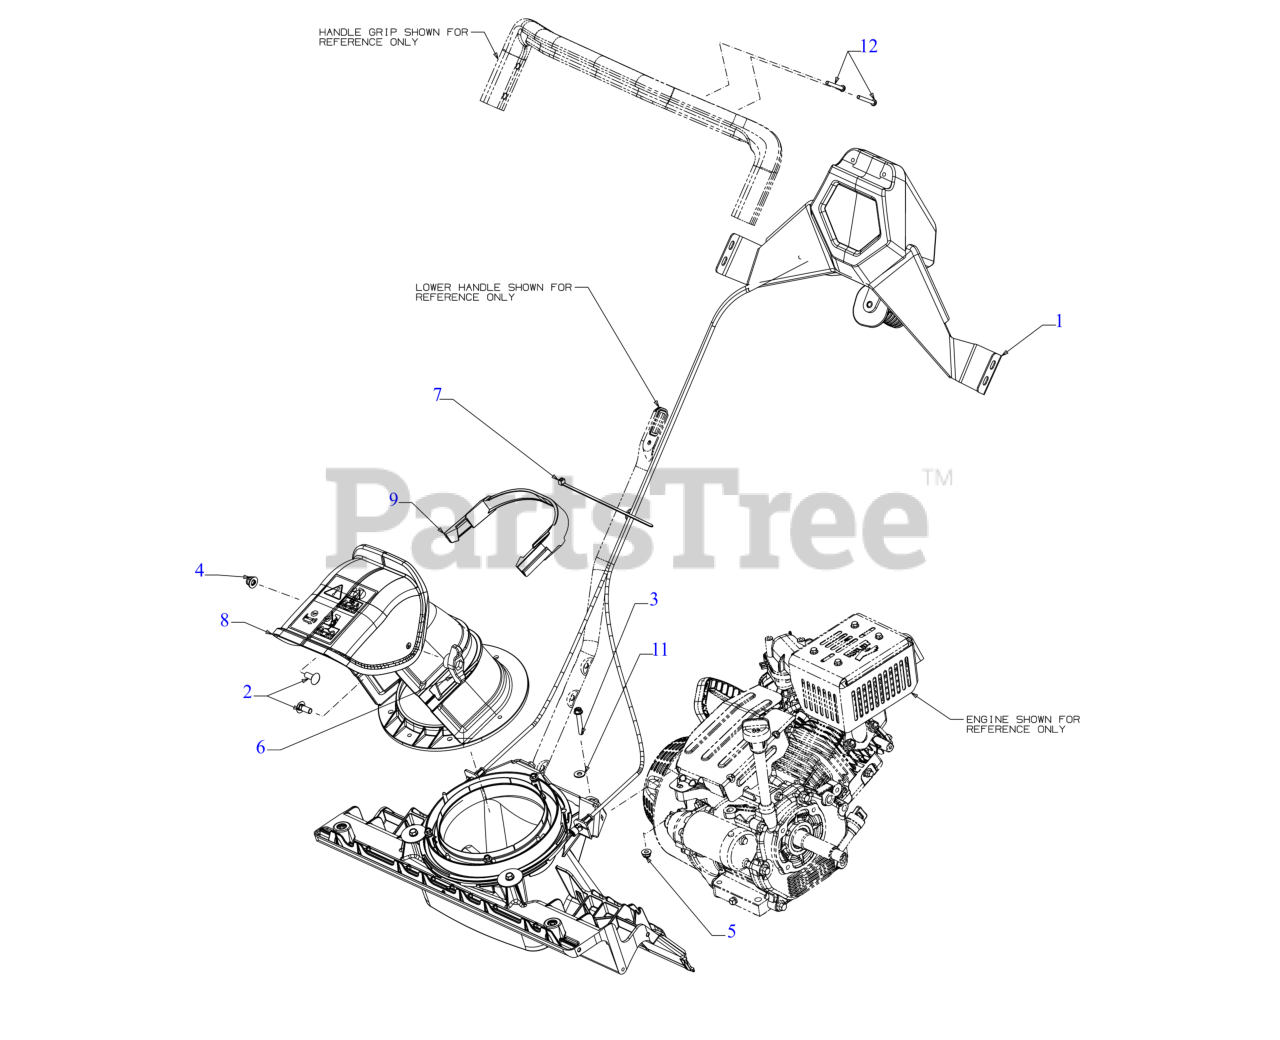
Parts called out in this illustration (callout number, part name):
1	CHUTE CRANK ASSEMBLY
2	CARRIAGE BOLT 5/16-18 x .75
3	HEX FLANGE BOLT 1/4-20 x 1.5
4	FLANGE LOCK NUT 5/16-18
5	FLANGE LOCK NUT
6	WING KNOB 5/16-18
7	7" CABLE TIE
8	UPPER CHUTE (W/LBL MANUAL TILT)
9	CHUTE PLUG
10	LOWER CHUTE 6.5"
11	FLAT WASHER
12	SCREW
